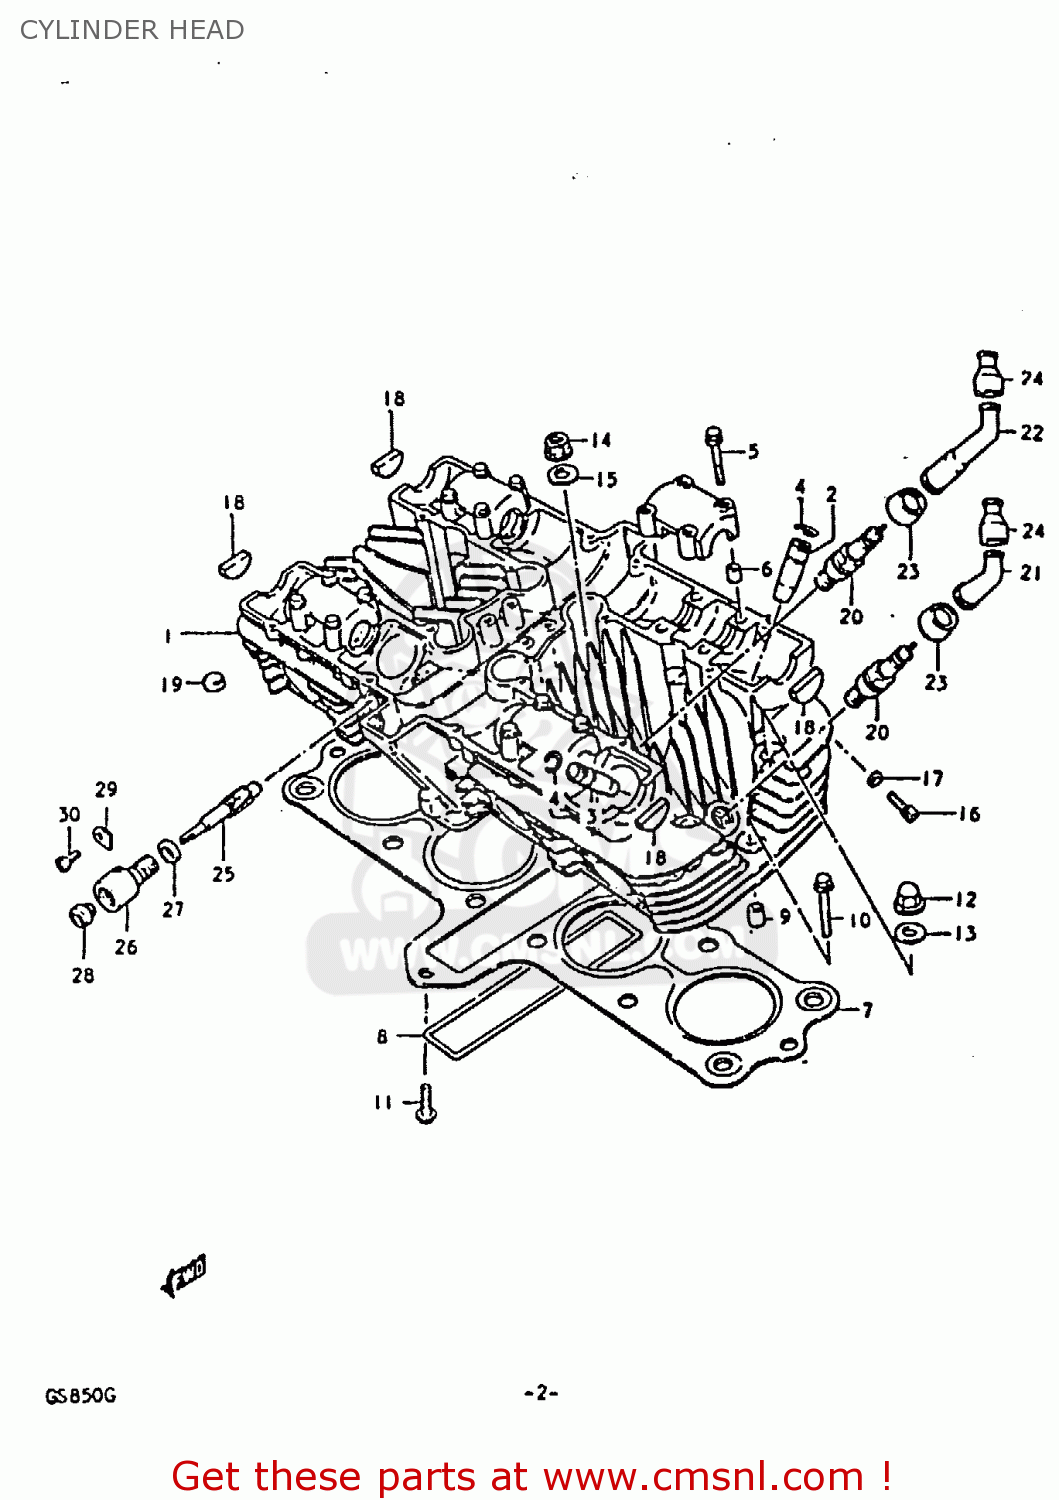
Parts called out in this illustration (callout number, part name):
1	HEAD ASSEMBLY,CYLINDER
2	GUIDE,VALVE
3	GUIDE,VALVE
4	RING,SNAP
5	BOLT(6X39)
6	PIN(6.2X8X11)
7	GASKET,CYLINDER HEAD (MCA)
8	O RING(D:3,ID:26X157)
9	PIN
10	BOLT,UNDER
11	BOLT
12	NUT
13	GASKET(10.5X22X2) (NAS)
14	NUT
15	WASHER(10.5X22X2.3)
16	BOLT
17	GASKET(5.3X9.3X1.2) (NAS)
18	PLUG
19	PAD
20	PLUG,SPARK
21	CAP,SPARK PLUG
22	CAP ASSY,SPARK PLUG
23	SEAL,SPARK PLUG
24	SEAL,SPARK PLU
25	GEAR,TACHOMETER DRIVEN
26	SLEEVE,TACHOMETER DRIVE
27	SEAL,TACHOMETER DRIVEN
28	SEAL,OIL(5X12X8)
29	PLATE,TACH DRIVE GEAR SLEEVE
30	SCREW(5X12)
